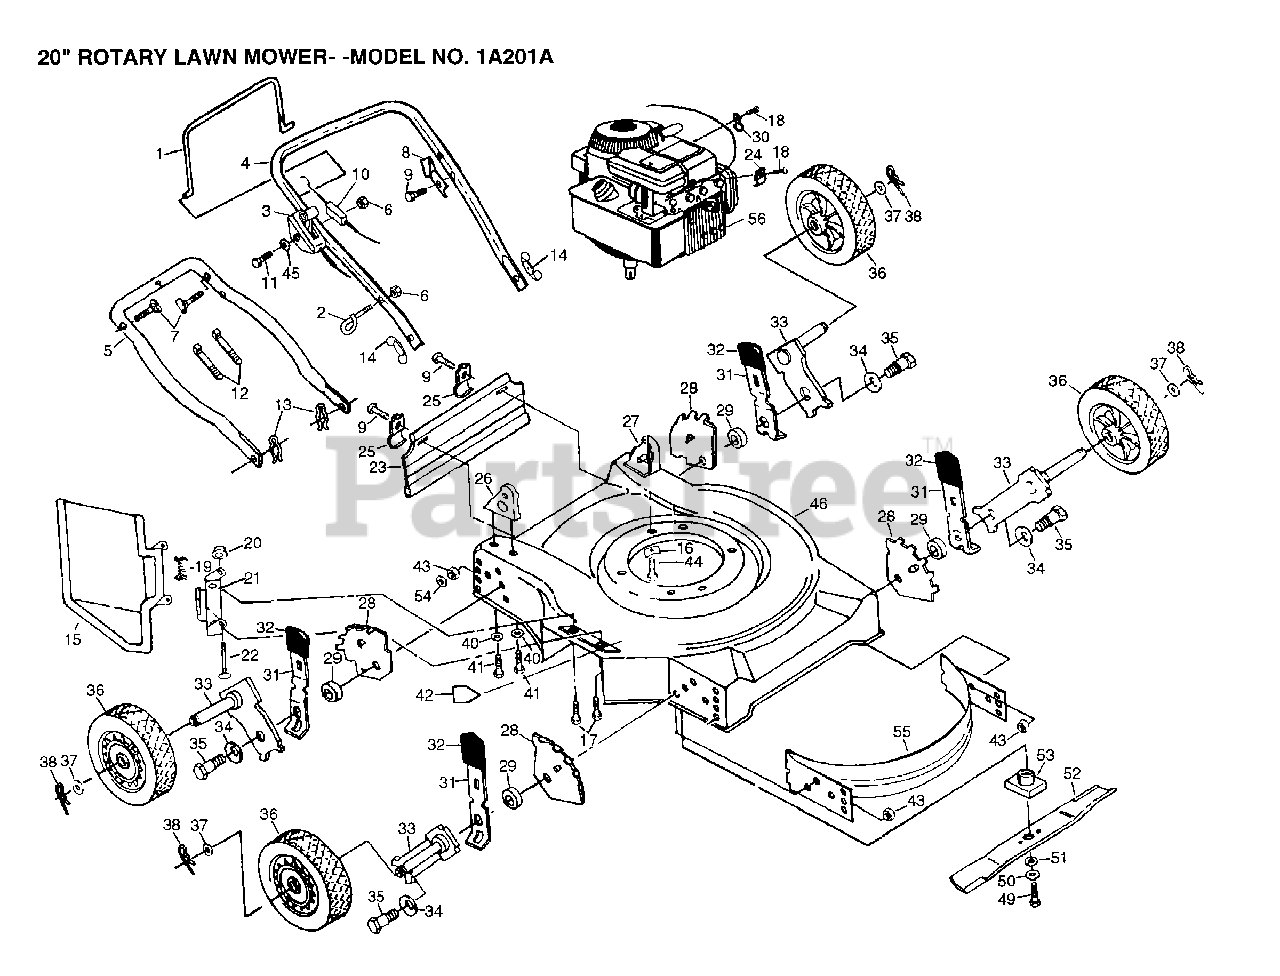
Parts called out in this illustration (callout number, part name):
1	CONTROL BAR PM
2	ROPE GUIDE
3	CONTROL THROTTLE
7	BOLT.HANDLE.LM
8	"BRKT,UPSTOP"
9	TAPPING SCREW
10	"CABLE,ENG ZONE CO"
13	HAIRPIN COTTER
14	"NUT,WING PM"
15	"GRD,DISCHARGE"
17	SCREW
18	SCREW PM
19	"SPRING,TORSION"
20	PUSH ON SPEED NUT
21	"BRKT,HSG "
24	CABLE CLAMP
25	"BRKT,DEFL PM"
30	"CLIP,CABLE"
32	KNOB PM
33	AXLE ARM
34	"WASHER, BELLEVIL."
36	WHEEL ASSY
37	WASHER
38	RETAINER CLIP PM
40	STEEL WASHER
41	SCREW
42	DECAL HYT
43	LOCKNUT PM
44	SCREW
45	WASHER PM
46	"KIT.HSG.20""SDPUSH"
49	SCREW
50	LOCKWASHER
51	"WASHER,HARDEN"
52	BLADE.STAND.20INC
55	BLADE ADAPTOR
